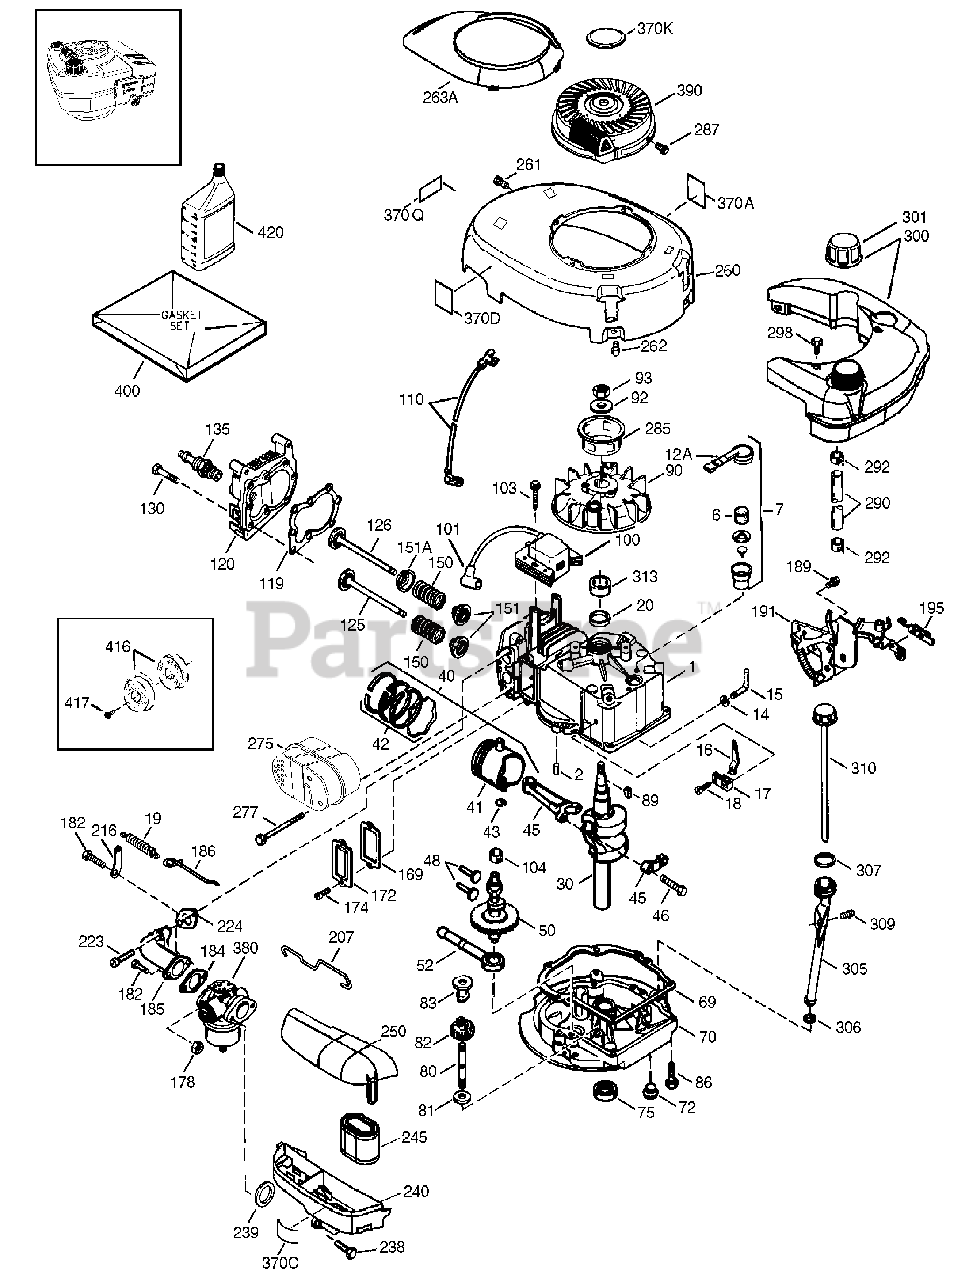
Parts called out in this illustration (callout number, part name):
1	Cylinder (Incl. 2, 20 & 150)
2	Dowel Pin
6	Element-Element
7	Breather Body ASM (Incl. 6 & 12A)
12A	Breather Cover & Tube
14	Washer
15	Governor Rod(Incl. 14)
16	Governor Lever
17	Clamp, Governor
18	Screw
19	Grip-Foot Pedal
20	&al, Oil
30	Crankshaft
40	Piston,Pin,Ring Set (Std.)
40	Piston,Pin,Ring Set (.010 OS)
41	Piston & Pin ASM(Std.)(Incl. 43)
41	Piston & Pin ASM(.010" OS)(Incl. 43)
42	FITTING - TANK 3/4"
42	FITTING - TANK 1"
43	Ring-Retaining
45	Connecting Rod ASM (Incl. 46)
46	Screw
48	Lifter Valve
50	Camshaft
52	Oil Pump ASM
69	Mounting FlangeGasket
70	Mounting Flange (Incl. 72 thru 83, 306)
72	Plug-Oil
75	Oil Seal
80	Governor Shaft
81	Washer
82	Governor Gear ASM (Incl. 81)
83	Spool-Govemor
86	Screw
89	THROTTLE TRIGGER ASM
90	Flywheel
92	Washer
93	Flywheel Nut
100	Solid State Ignition
101	Cover Spark Plug
103	Screw
104	Cam Bushing
110	Ground Wire
119	Cylinder Head Gasket
120	Cylinder Head
125	Exhaust Valve (Std.)(Incl. 151)
126	Intake Valve (Std.)(Incl. 151)
130	Screw
135	Spark Plug (RJ19LM)
150	Spring Valve
151	Cap-Valve Spring
151A	BEARING - TRANS
169	Valve Cover Gasket
172	Valve Cover
174	Screw
178	Nut
182	Screw
184	Gasket-Carburetor
185	61749 TRACT.CONV.KI
186	Governor Link
189	Screw
191	S.E. Brake Bracket (Incl. 195)
195	Terminal
207	Link-Throttle
216	Lever, RPM Adjusting
223	Screw
224	Intake Pipe Gasket
238	Screw
239	Air Cleaner Gasket
240	Air Cleaner Body
245	Washer
250	Air Cleaner Cover
260	Blower Housing
261	Screw
262	Screw
263A	Starter Grill
275	Muffler
277	Screw
285	Starter Cup
287	Screw
290	Fuel Line
292	Clamp Fuel Line
298	Screw
300	Fuel Tank (Incl. 292 & 301)
301	Cap Fuel
305	Oil Fill Tube
306	"O"-Ring
307	O-Ring
309	Screw
310	Dipstick
313	Spacer
370A	Decal-Instruction
370C	Primer Decal (3X)
370D	Caution Decal
370K	Emblem Decal
370Q	Emissions Decal
380	Carburetor (Incl. 184)
390	Rewind Starter
400	Gasket Set
416	Spark Arrestor Kit
417	Screw
420	SAE30 4-Cycle Engine Oil (Quart)
